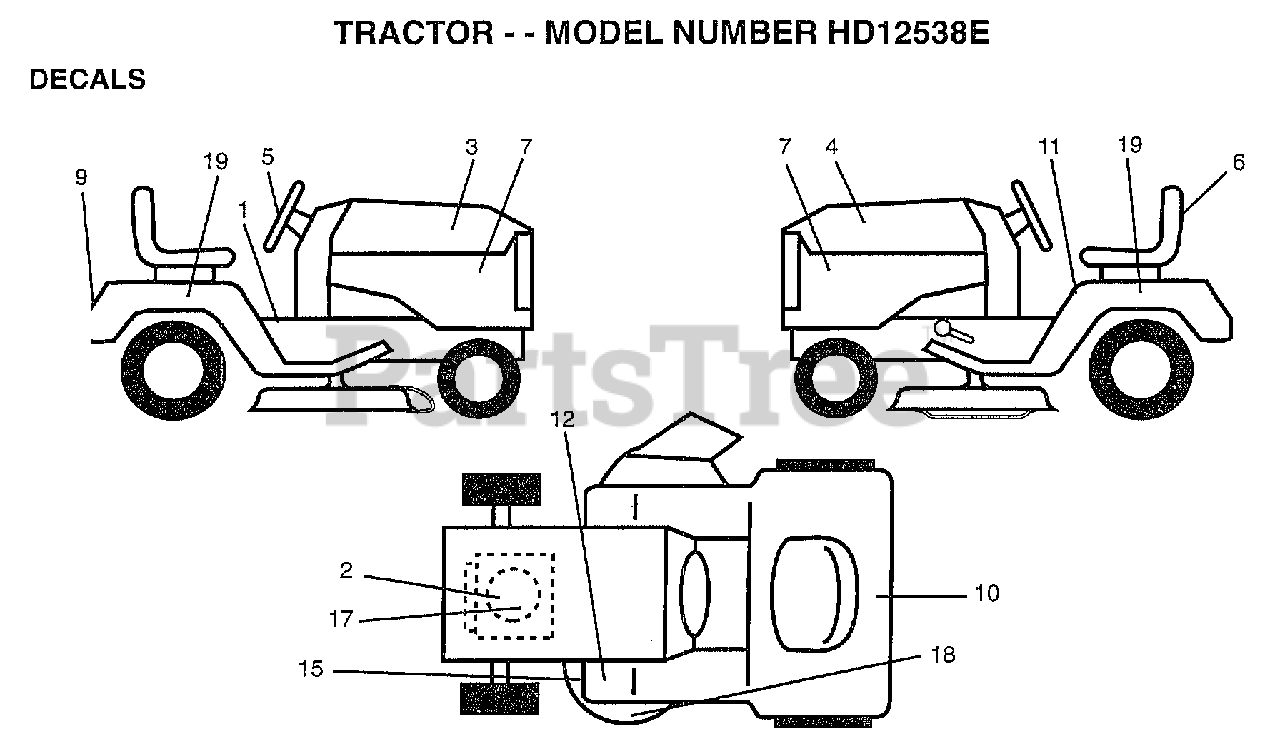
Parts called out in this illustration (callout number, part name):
2	DECAL, HP ENGINE
3	DECAL.HOOD.RH.
4	DECAL.HOOD.LH
5	DECAL, INS STRG WH
7	DECAL.PANEL.SD.SP
9	DECAL.FENDER.LOGO
10	DECAL.BATRY.3-3908
11	"DECAL FENDER,DANG"
12	DECAL CLUT/BRAKE
15	DECAL
17	DECAL.ENGINE.REPL
18	DECAL.MOWER.HOME
19	DECAL.FEND.SD.5SP
